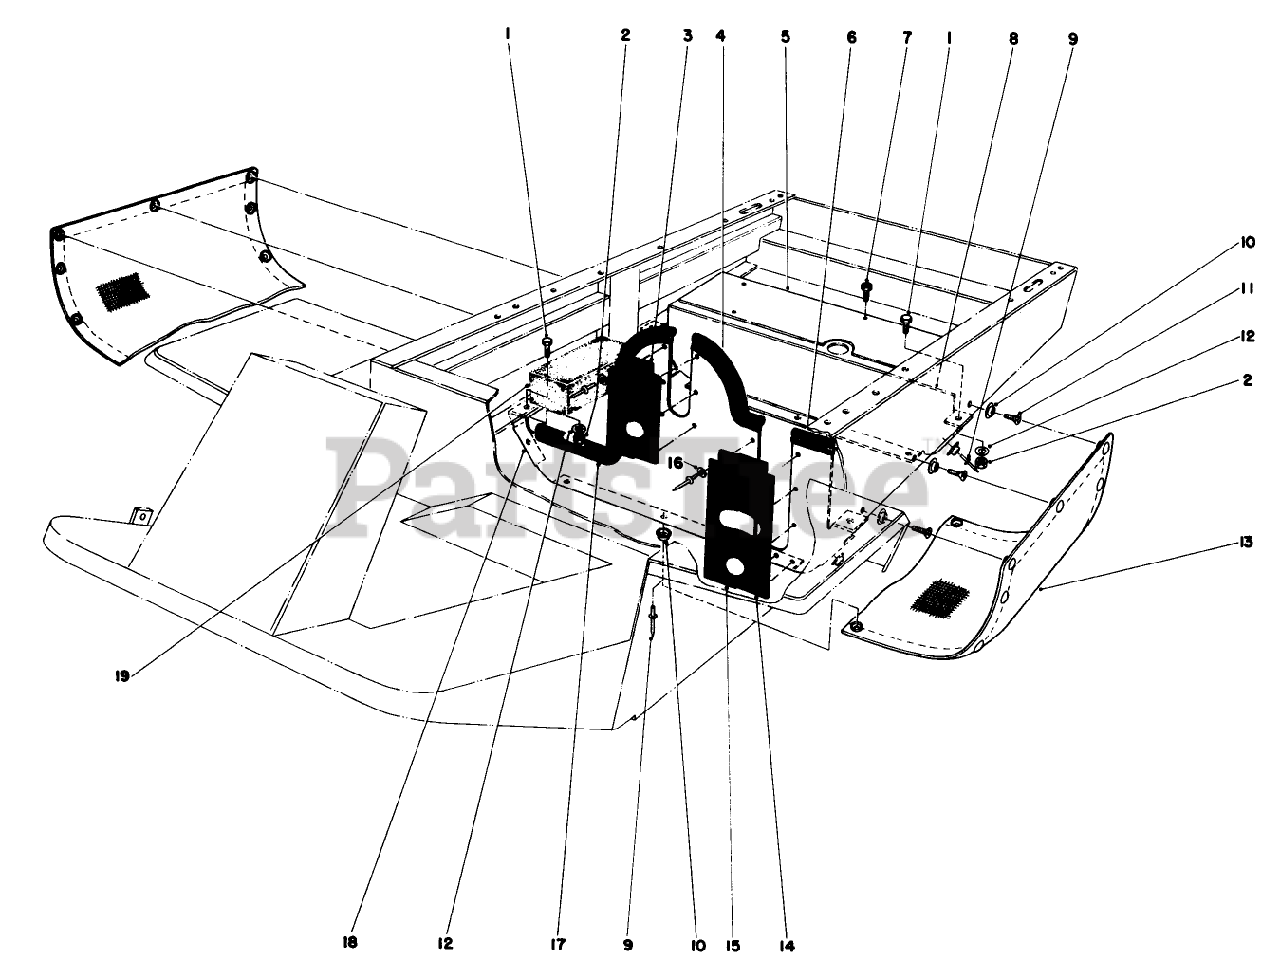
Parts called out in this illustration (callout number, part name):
1	SCREW-HH
2	NUT-HEX
4	TRIM SEAL
5	Grass Shield-Engine
6	TRIM SEAL
7	SCREW-HH
8	Shield Assembly Rear (Incl. Ref. #9 & 10)
9	RIVET-POP
10	SNAP STUD
11	Self Tapping Screw
12	WASHER-LOCK/SP
13	GRASS SCREEN BAG
14	LH FLAP
15	RH FLAP
16	WASHER
17	TRIM SEAL
18	Shield Assembly Front (Incl. Ref. #3-4, 6, 9-10 & 14-18)
19	SIDE FOAM
